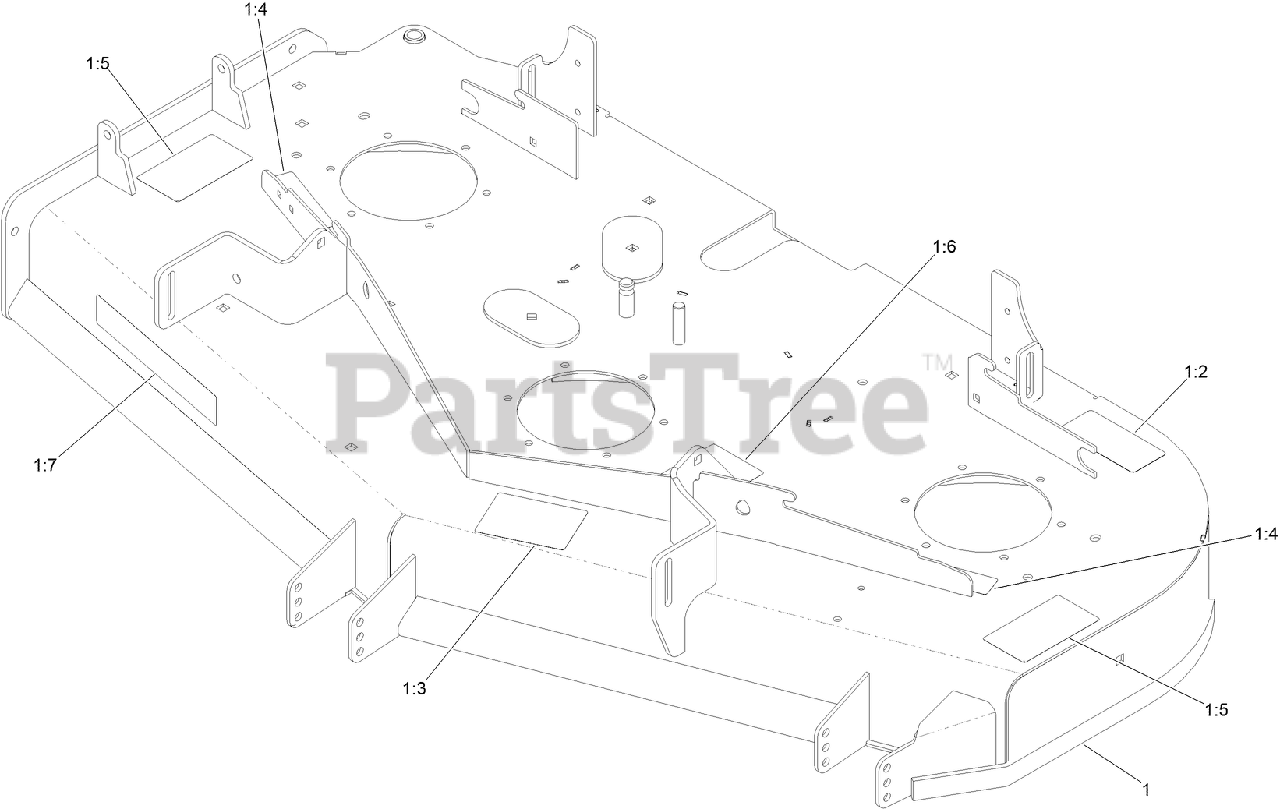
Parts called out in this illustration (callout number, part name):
1	DECK DECAL ASM
1:2	DECAL-TORQUE, BLADE BOLT
1:3	DECAL-SCALP, ANTI
1:4	DECAL-COVER, MISSING
1:5	DECAL-DANGER
1:6	DECAL-ROUTING, BELT
